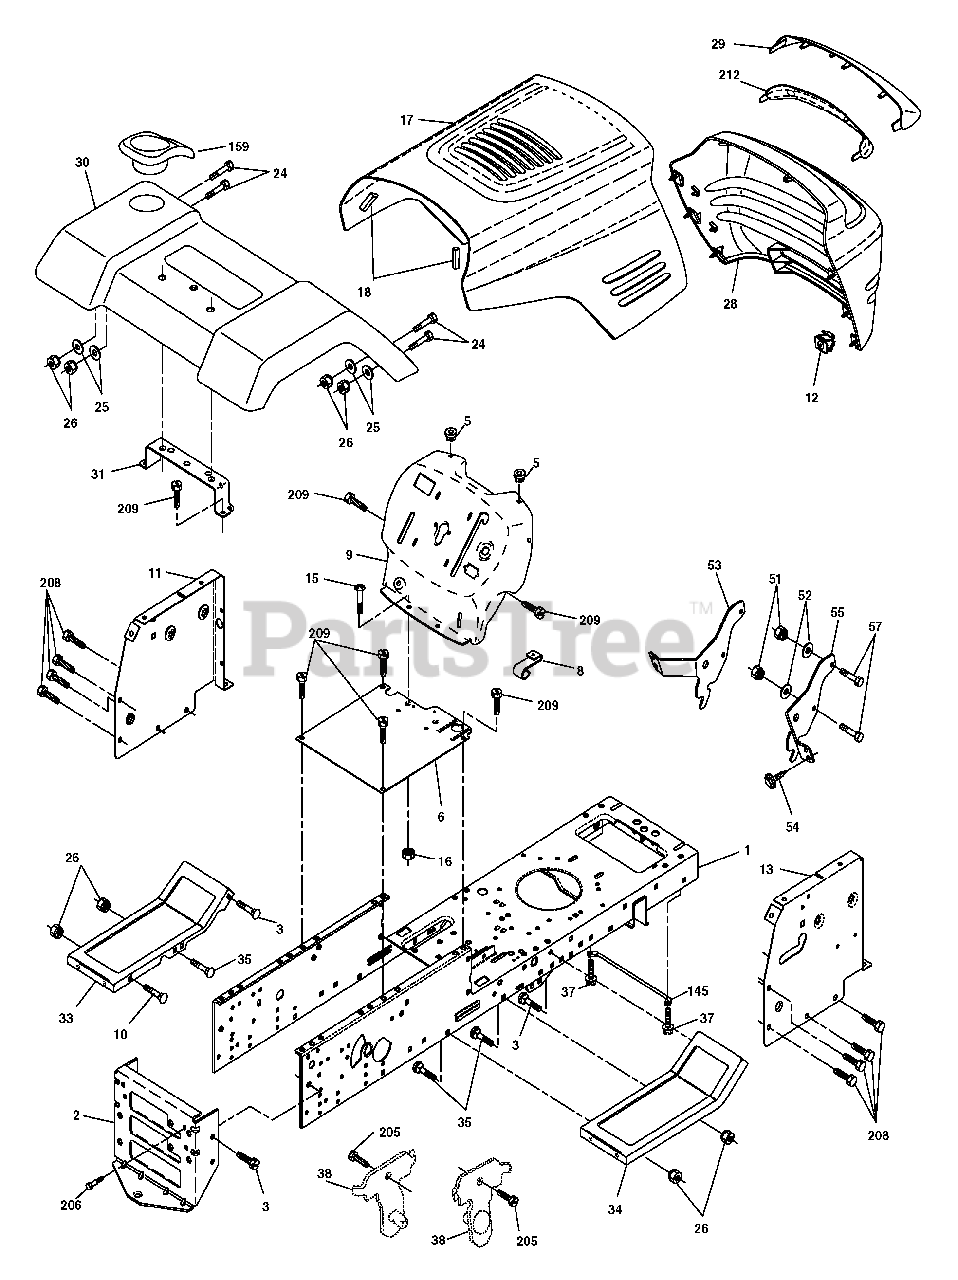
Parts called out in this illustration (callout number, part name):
1	Chassis
2	Drawbar
3	Screw 3/8-16 x 3/4
5	Bumper Hood/Dash
6	Saddle Slkscr Flat Lt 6 Sp
8	Clip Retainer Slide-On
9	Dash
10	Bolt Rd Hd Sqnk. 3/8-16 Unc x 1
11	Panel Asm. Dash Lh
12	Clip Tinnerman Grile P/L
13	Panel Dash Rh
15	Screw Mach Trhd 5/16-18 Unc x 3/4
16	Nut Keps 5/16-18 Unc
18	Bumper Hood
24	Bolt Fin Hex 3/8-16 Unc x 1 Gr. 5
25	Washer 13/32 x 13/16 x 12 Ga.
26	Nut Lock Hex w/Insert 3/8-16 UNC
28	Grill/Lens Asm
29	Lens Grille
31	Bracket Fender
35	Bolt Rd Hd Sht. Sqnk. 3/8-16 x 3/4
37	Screw Thdrol 5/16-18 x 1/2 Tyt
38	Bracket Asm. Pivot Mower Rear
51	Nut Lock Hex W/Ins. 1/4-20
52	Washer 9/32 x 7/8 x 16 Ga.
53	Bracket Grille LH
54	Screw Hex Wshd 8-18 x 7/8
55	Bracket, Grille RH
57	Bolt Fin Hex 1/4-20 x .75
145	Rod Pivot Chassis/Hood
159	Cup Holder
205	Screw Thdrol 3/8-16 x 1/2
206	Bolt shoulder 5/16-18
208	Screw Thdrol 3/8-16 x 1/2
209	Screw Hex Wsh Thdrol 3/8-16
212	Insert Lens Reflector
